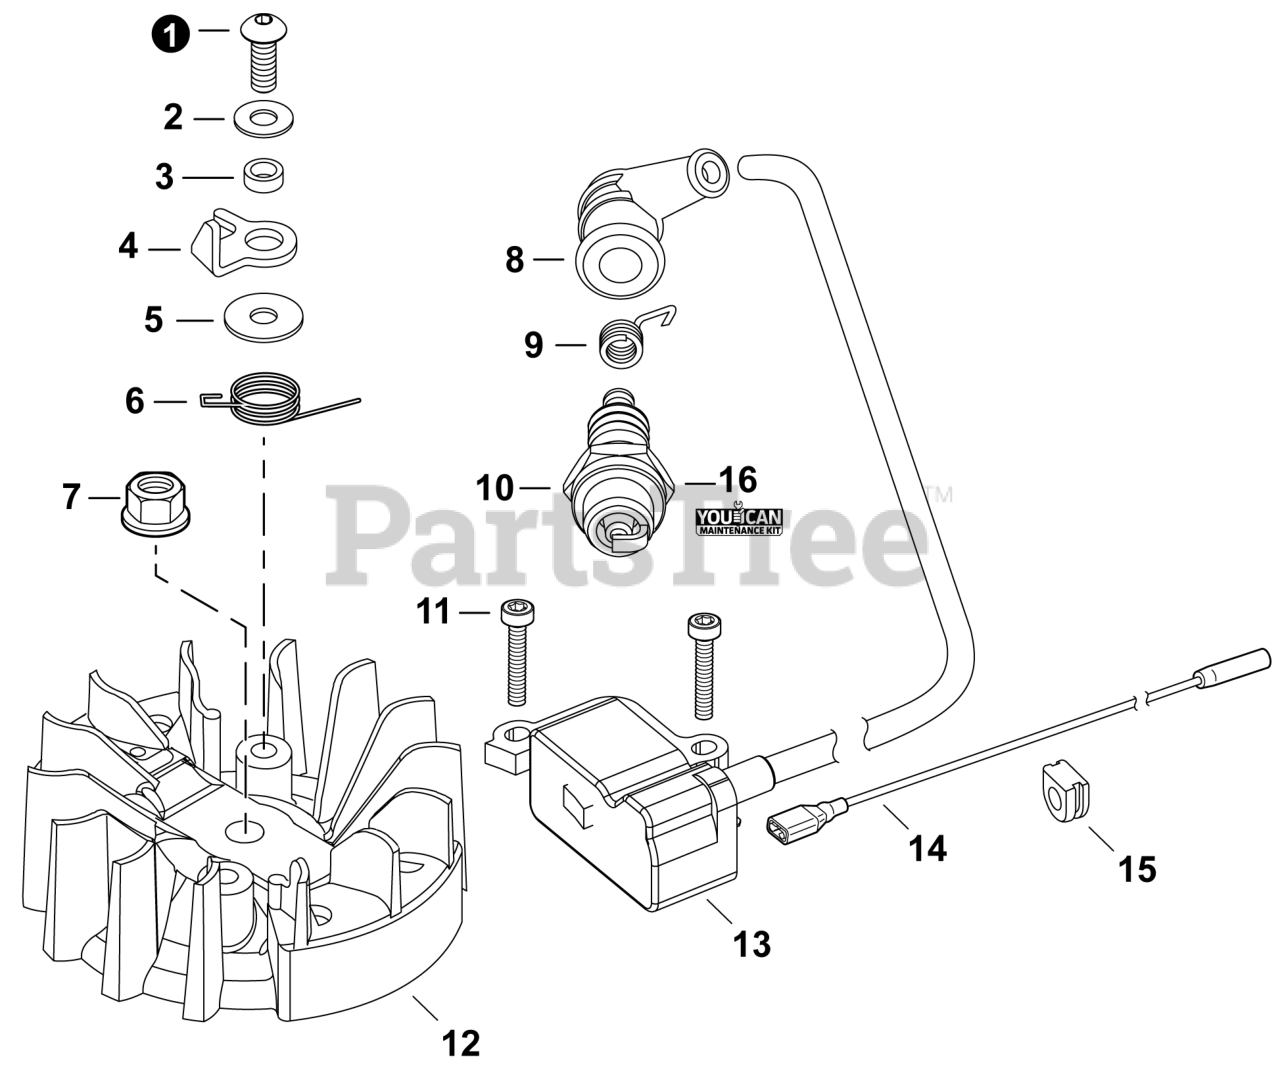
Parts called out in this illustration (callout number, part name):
1	BOLT 5x14
2	WASHER 5.5x12x0.8
5	WASHER 5.5x16x0.8
6	SPRING, TORSION
7	NUT, FLANGE M6
8	CAP, SPARK PLUG
9	TERMINAL, SPARK PLUG
10	SPARK PLUG - BPMR8Y
11	BOLT, TORX 4x16
12	FLYWHEEL
13	COIL, IGNITION
14	LEAD L= 85 MM
16	TUNE-UP KIT - YOUCANT
